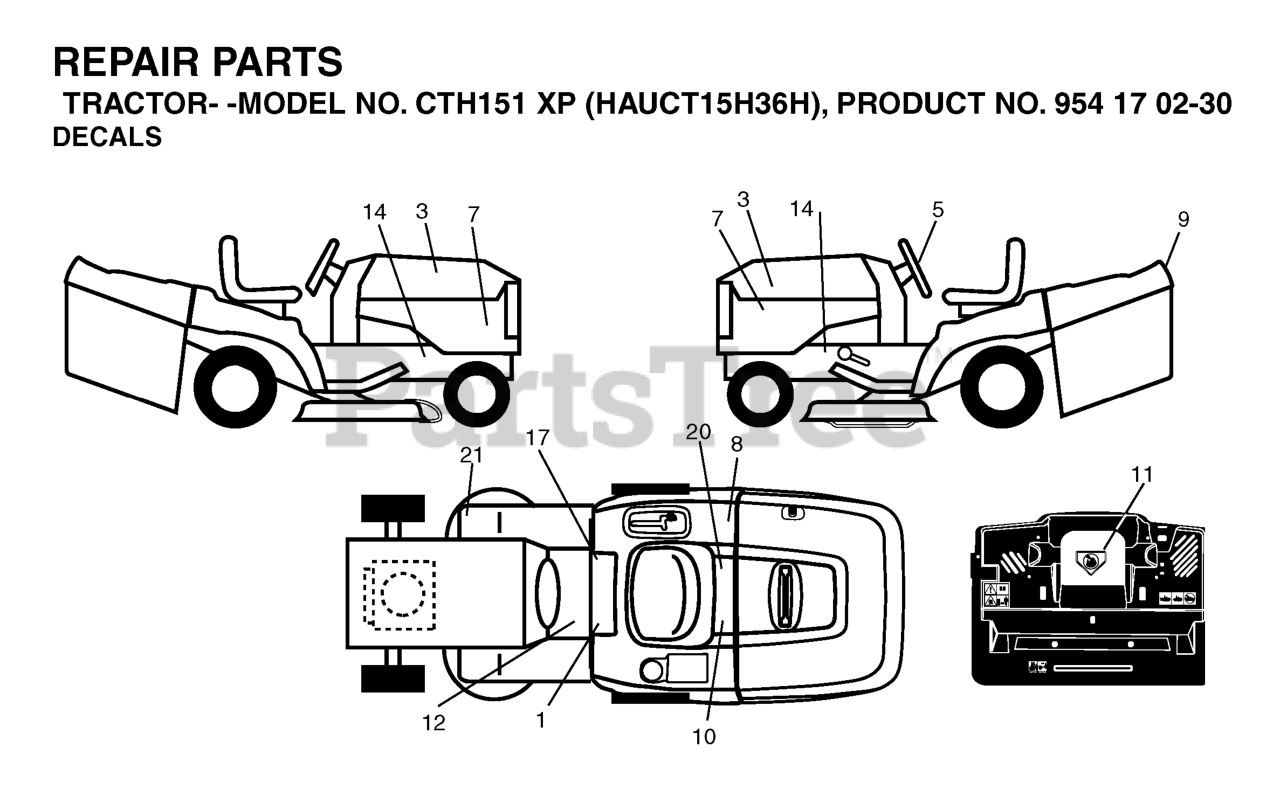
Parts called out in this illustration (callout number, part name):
1	DECAL READ OWNER'S MAN SYMS
3	DECAL.HOOD.HUSQVARNA.INTERNATI
5	DECAL.STEERING.HUSQ.BLUE
8	DECAL
10	DECAL BTRY SYMBOLS
11	DECAL.INTERNATIONL.CUTFINGER
12	DECAL
17	DECAL PARK BRAKE
20	DECAL.BYPASS.FENDER.CRD.LT.YT
